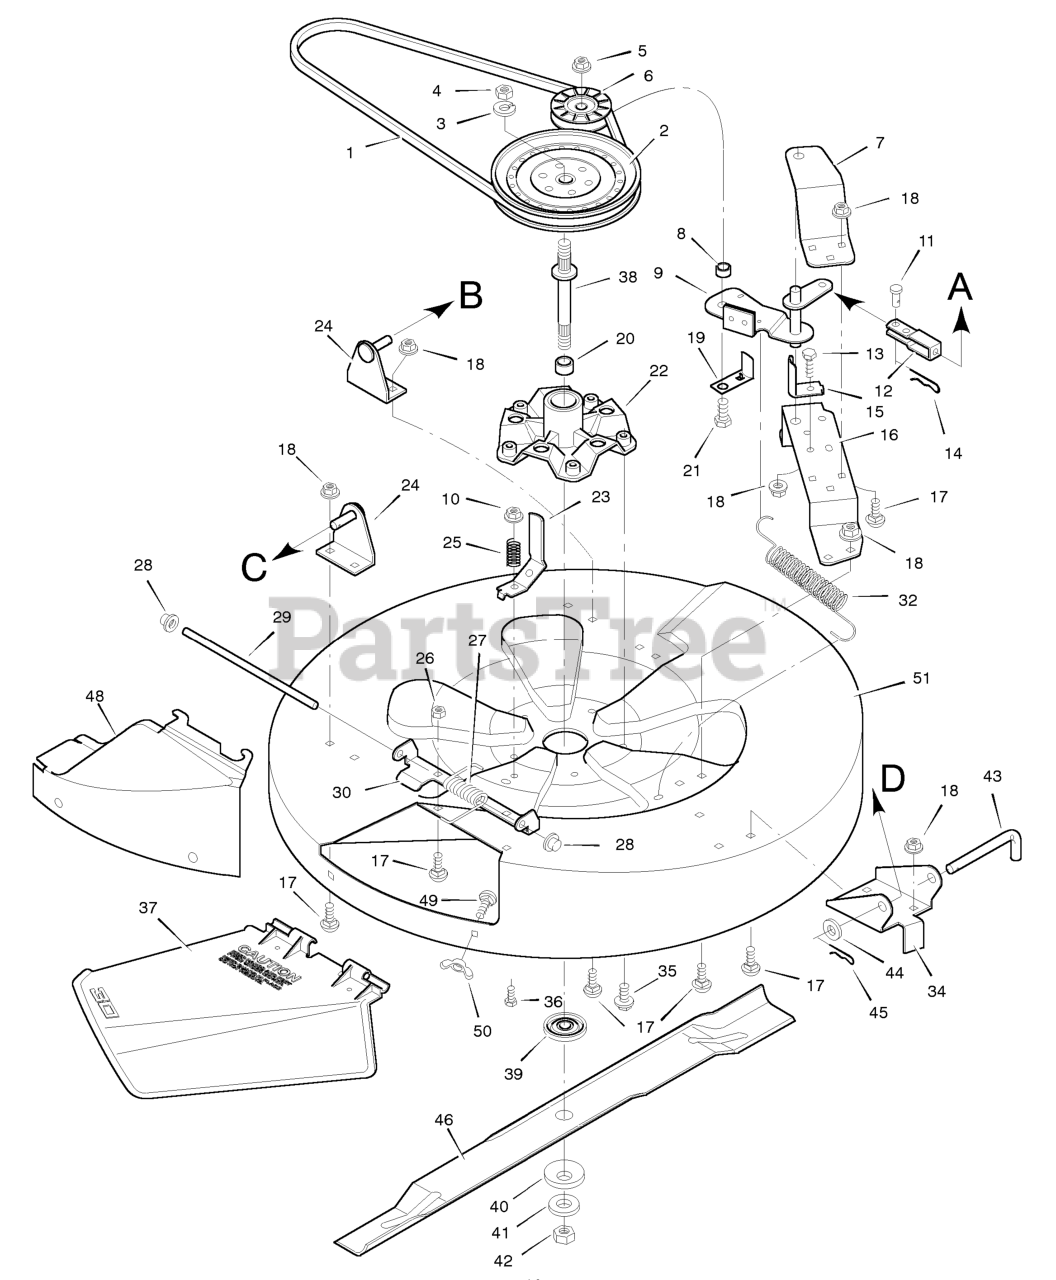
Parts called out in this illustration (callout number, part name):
1	Belt, Mower Drive
2	Pulley, Splined
3	Lockwasher
4	Locknut, Hex
5	Nut, Hex
6	Pulley, Idler
7	Bracket, Upper Idler
9	Assembly, Blade Idler
10	Locknut, Flange
11	Pin, Clevis
12	Clevis Hex
13	Bolt,
14	Pin, Hair
15	Guide, Belt
16	Bracket, Lower Idler
17	Bolt, Carriage
18	Nut, Flange
19	Guide, Belt
21	Bolt, Hex
22	Housing, Mandrel
23	Guide, Belt
24	Bracket, Hanger
25	Spring, Compression
26	Nut, Hex
27	Spring - Torsional
28	Push On Cap
30	Hinge, Chute Deflector
32	Spring, Extension
34	Bracket, Front
36	Bolt, Hex
37	Deflector, Chute
38	Mandrel
39	Adapter, Blade
40	Washer, Belleville
41	Washer, Hardened
42	Nut, Hex
43	Pin, Pull
45	Pin, Hair Standard
47	Blade, Mulcher
48	Plate, Mulcher
49	Bolt, Carriage
50	Wingnut
